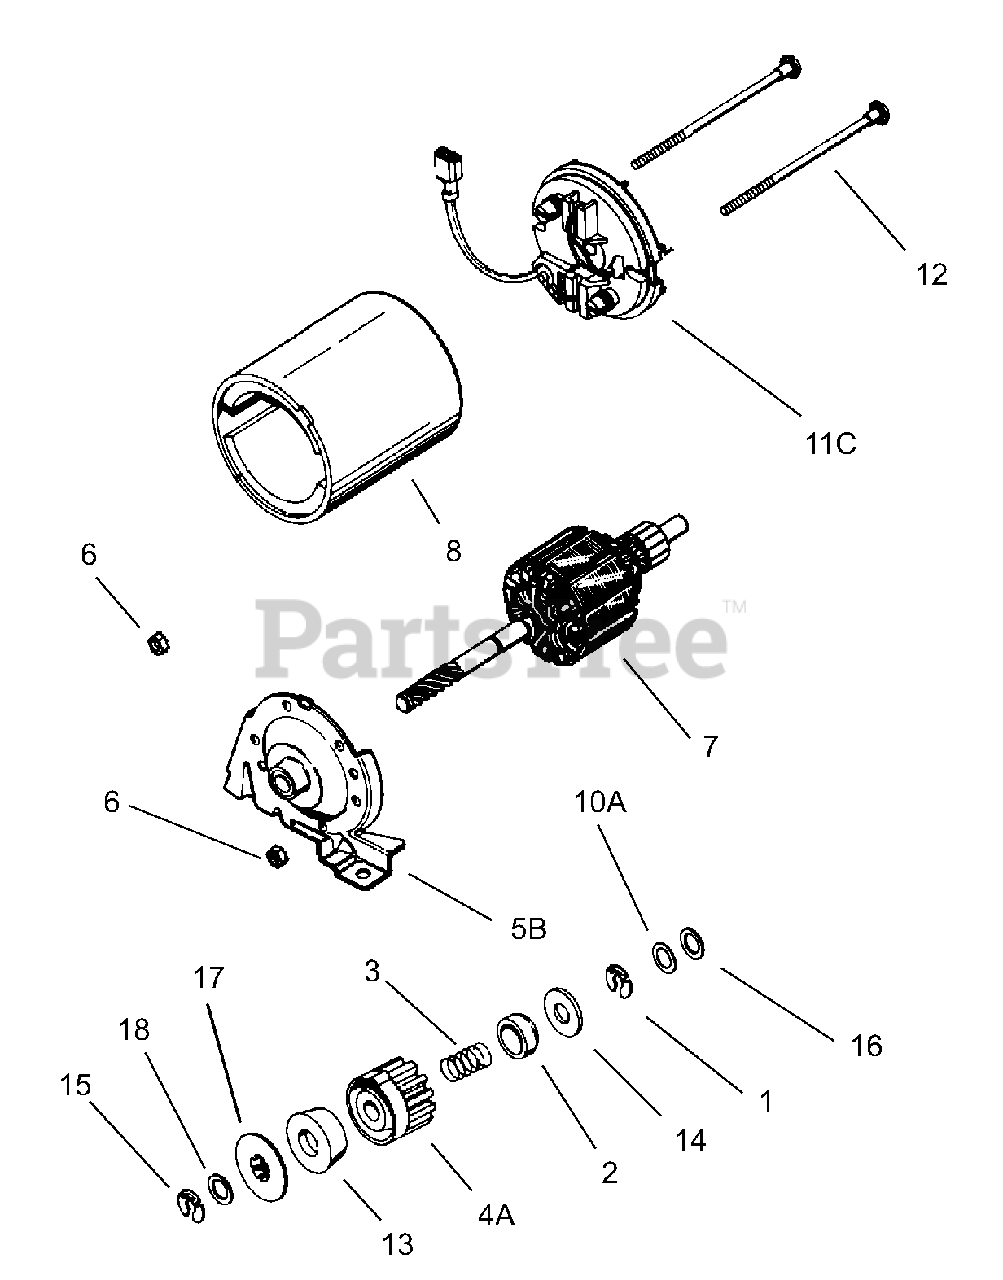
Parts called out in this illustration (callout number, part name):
1	Retainer Ring
2	Spring Retainer
3	Spring
4A	Gear
5B	Drive End Cap Ass'y.
6	Lock Nut
7	Armature
8	Housing Ass'y.
10A	Thrust Washer
11C	Commutator End Cap Ass'y. (Incl. brushes)
12	Bolt, 10-32 x 3-3/16"
13	Pinion Driver
14	Cup Washer
15	Retainer Ring
16	Washer
17	Drive Nut
18	Washer
